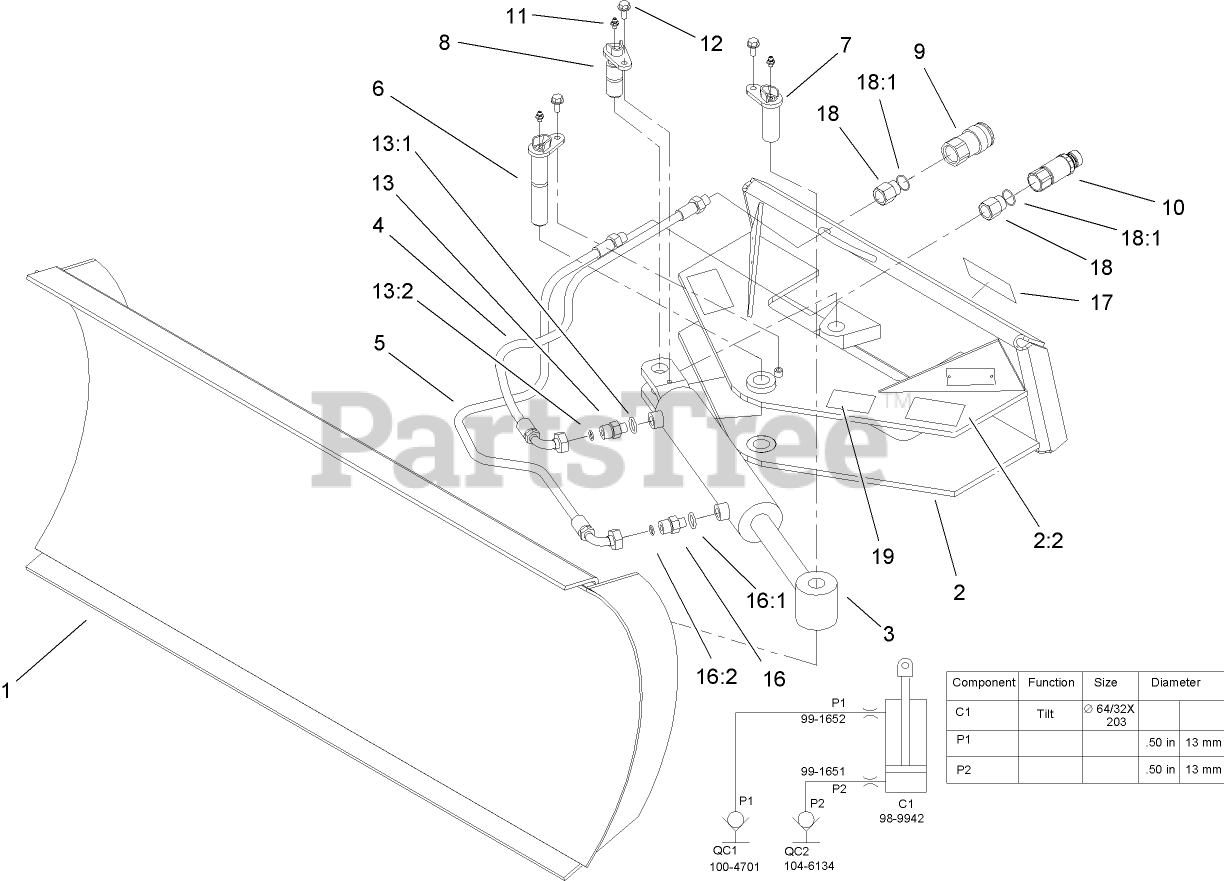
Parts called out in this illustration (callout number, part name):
1	Blade ASM
2	Blade Pivot ASM
2:2	DECAL-WARNING
3	CYLINDER-HYD
4	HYD HOSE ASM
5	HYD HOSE ASM
6	PIN-PIVOT
7	PIN-PIVOT
8	PIN-PIVOT
9	COUPLER-FACE, FLUSH
10	NIPPLE-CONNECT, PRESSURE
11	FITTING-GREASE
12	BOLT-SHOULDER
13	FITTING-STR
13:1	O-RING
13:2	O-RING
16	CONNECTOR-STRAIGHT
16:1	O-RING
16:2	O-RING
17	Decal
18	ADAPTER-HYD
18:1	O-RING
19	DECAL
